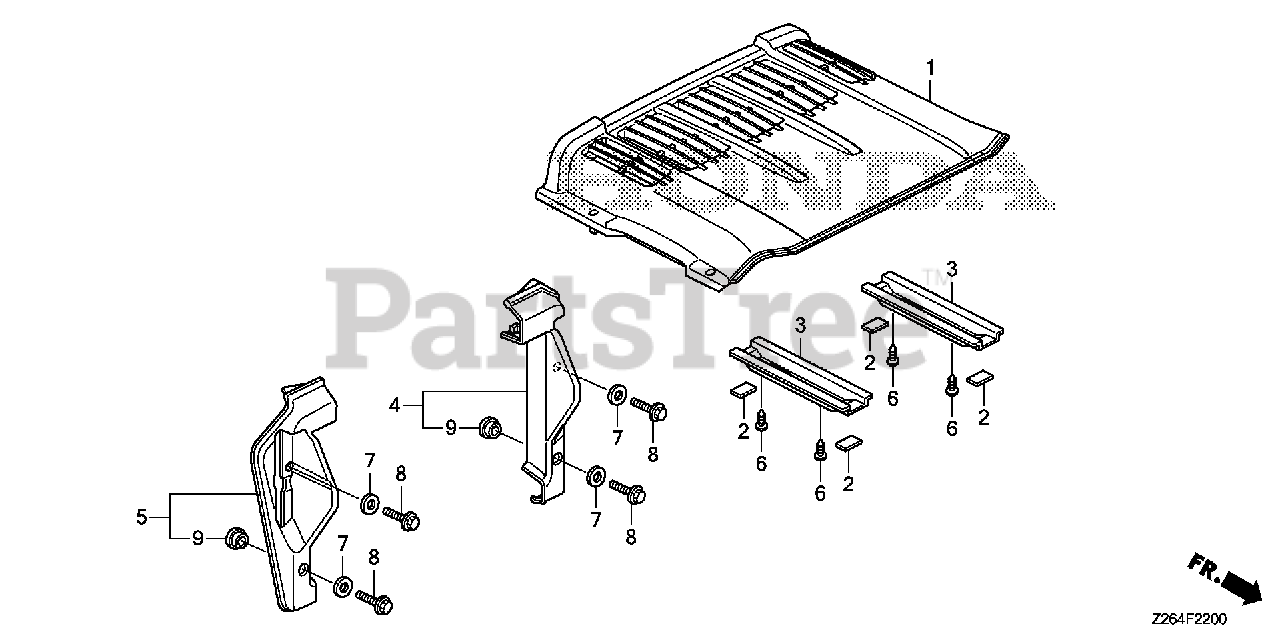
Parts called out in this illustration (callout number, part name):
1	COVER, MAINTENANCE *R280* (POWER RED)
2	SHEET, MAINTENANCE COVER
3	BEAM, MAINTENANCE COVER
4	COVER, R. SIDE *TBLACK* (BLACK)
5	COVER, L. SIDE *TBLACK* (BLACK)
6	SCREW, TAPPING (5X14) (PO)
7	WASHER, PLAIN (6MM)
8	BOLT, FLANGE (6X25)
9	COLLAR, SIDE COVER
